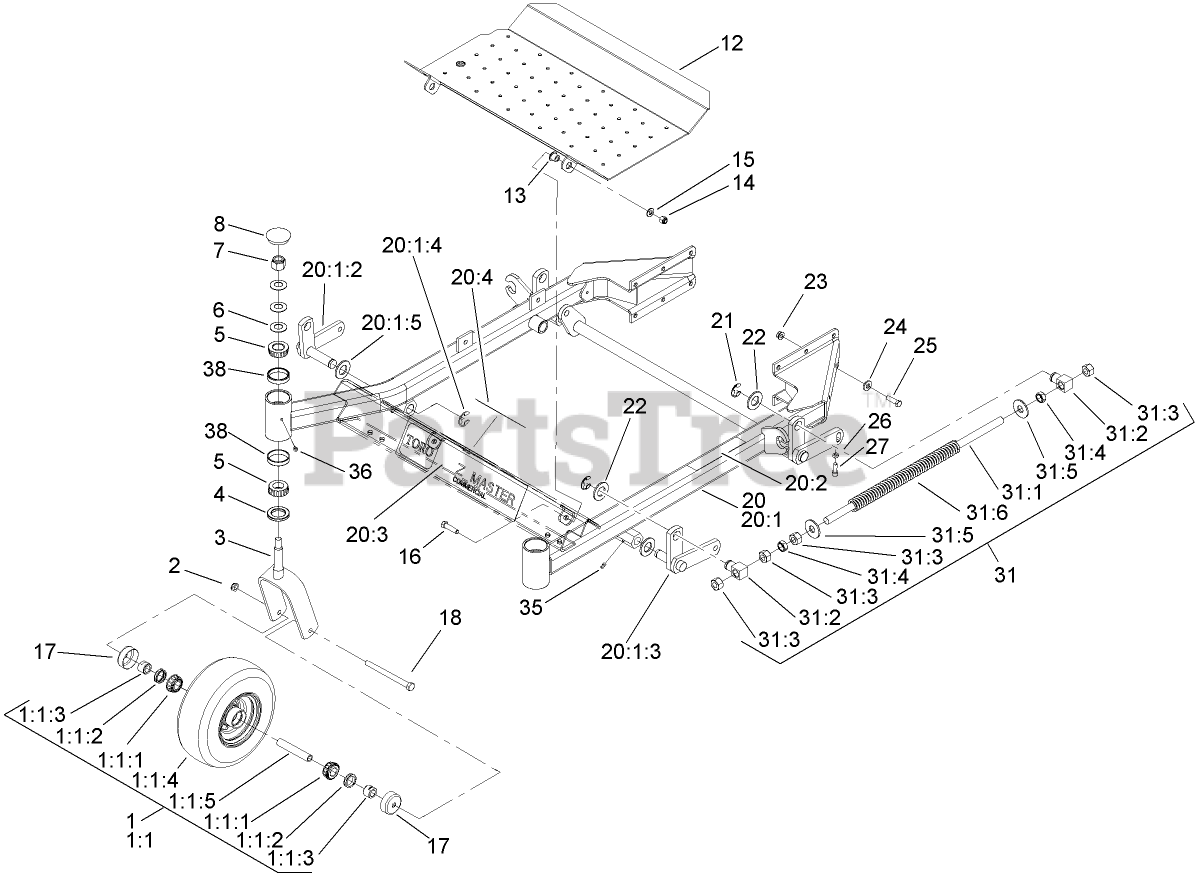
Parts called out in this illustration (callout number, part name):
1	WHEEL AND TIRE ASM
1:1	WHEEL AND BEARING ASM
1:1:1	BEARING-CONE, TAPER
1:1:2	SEAL-CASTER
1:1:3	SPACER-NUT
1:1:4	WHEEL AND TIRE ASM
1:1:5	AXLE-CASTER
2	NUT-LOCK, NI
3	CASTER FORK ASM
4	SEAL-GREASE
5	BEARING-CONE, TAPERED
6	WASHER-BELLVILLE
7	NUT-LOCK, NI
8	CAP-GREASE
12	FLOOR PAN
13	BUSHING-FLANGE
14	NUT-LOCK, NI
15	WASHER-FLAT
16	SCREW-HH
17	GUARD-SEAL
18	SCREW-HH
20	FRONT FRAME ASM
20:1	FRAME-FRONT
20:1:2	RH LIFT ARM ASM
20:1:3	LH LIFT ARM ASM
20:1:4	RING-RETAINING, EXT
20:1:5	WASHER-FLAT
20:2	DECAL-WARNING
20:4	DECAL-WARNING
21	RING-RETAINING, EXT
22	WASHER-FLAT
23	NUT-HHF, WHIZ
24	WASHER-BELLEVILLE
25	SCREW-HH
26	NUT-JAM
27	SCREW-HSH
31	FRONT FRAME SPRING ASM
31:1	ROD-LIFT, DECK
31:2	SWIVEL-DECK MOUNT, REAR
31:3	NUT-HEX
31:4	NUT-JAM
31:5	WASHER-FLAT
31:6	SPRING-SUPPORT, DECK
35	FITTING-GREASE
36	FITTING-GREASE
38	BEARING-CUP, TAPERED
